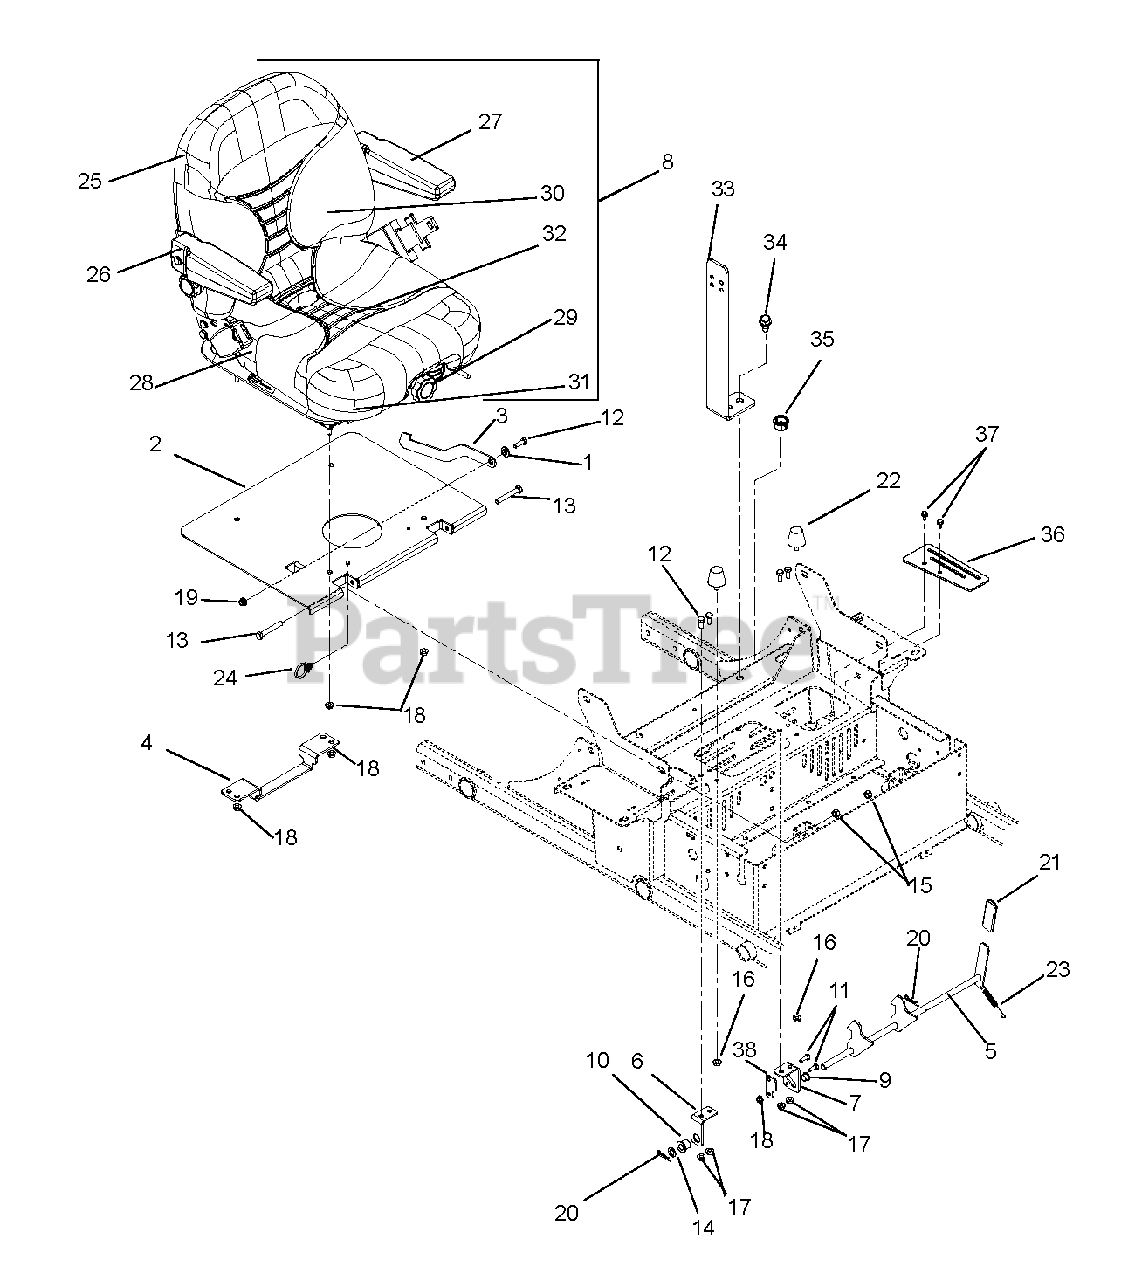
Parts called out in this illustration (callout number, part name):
1	Bushing, Flange .325 x .499 x .26 x .88
2	Seat Plate Weldment – Black
3	Stop, Seat Pivot
4	Bracket, Seat Latch
5	Weldment, Seat Latch
6	Mount, Seat Latch – Right Hand
7	Mount, Seat Latch – Left Hand
8	Seat, SUSP, with Seat Belt, Light Gray
9	Bushing, Polyliner – .50 Split
10	Bushing, Flange .515 x .750 x .745 x 1.00NY
11	Bolt, Hex .25-20 x .75 GR5 YWZC
12	Bolt, Hex .31-18 x .75 GR5 YWZC
13	Bolt, Hex .38-16 x 2.50 GR5 YWZC
14	Washer, Flat Steel .52 x .827 x .062 YWZC
15	Nut, Locking Center .38-16 YWZC
16	Nut, Spin Lock Flange .312-18 YWZC
17	Nut, Locking Top Flange .31-18 YWZC
18	Nut, Locking Top Flange .25-20 YWZC
19	Nut, Locking Nylon Flange .31-18 YWZC
20	Pin, Hair Internal .08 x .38 x 1.42 YWZC
22	Bumper, Rubber Cone, Stud Mount
23	Spring, Tension .043 x .44 x 3.31 WLD 5.8
24	Cable Tie with Tree (.25 HOLE)
25	Kit, Back Cushion, Light Gray
26	Kit, Armrest Assembly – Right Side
27	Kit, Armrest Assembly – Left Side
28	Kit, Seat Cushion, Light Gray
29	Kit, Seat Knobs
30	Kit, Seat Back
31	Kit, Seat Slides
32	Kit, Seat, Spring and Saddle
33	Mount, Switch PT200 CE
34	Screw, Tapping .31-18 x .50 Hex Washer Head Thread Rolling (lubricated or waxed)
35	Bushing, Panel Snap .687 x .875 x .56
36	Guard, Seat Plate Finger
37	Screw, Tapping .25-20 x .50 Hex Washer Head Thread Rolling
38	Retainer
